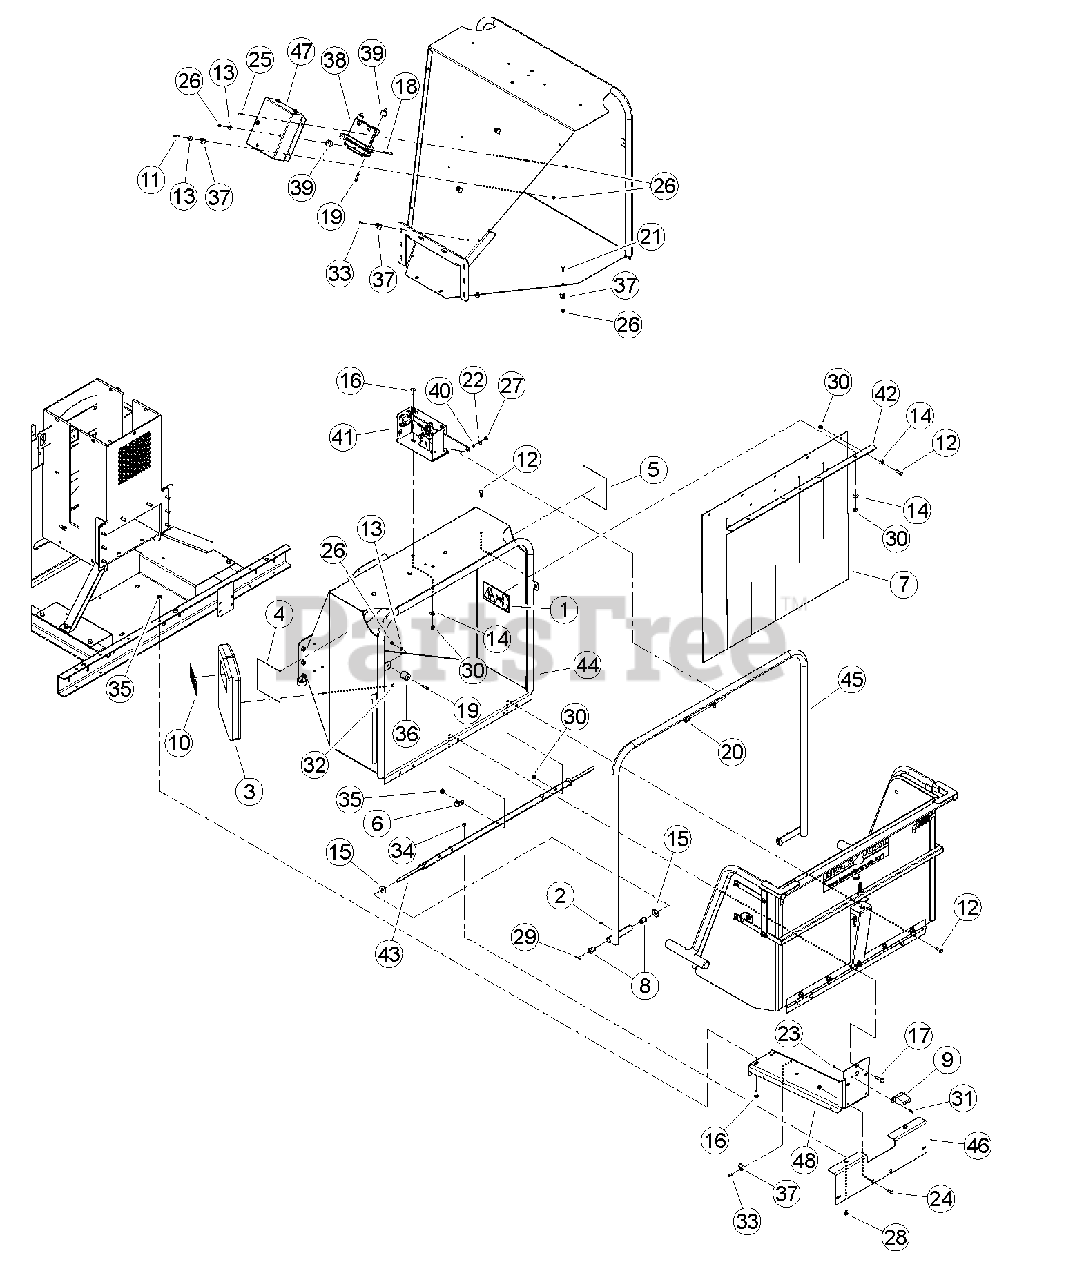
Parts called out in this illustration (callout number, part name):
1	DECAL, BLADE DANGER ISO
2	FITTING, 1/4 SELF-TAP GREASE
3	CONTAINER, INSTR. MANUAL
4	DECAL, FEED POSITION
5	DECAL, FEED POSITION
6	CLAMP, 9/16 COATED
7	FLAP, CHUTE
8	BUSHING, 1/2 X 1 FLANGE LUBE
9	LIGHT, LICENSE PLATE
10	DECAL, MUTILINGUAL MANUAL
11	BOLT, 1/4 X 1 GR5 HEX HD ZP
12	BOLT, 3/8 X 1 HEX HD GR5 ZP
13	WASHER, 1/4" FLAT ZP
14	WASHER, 3/8" FLAT ZP
15	WASHER, 1/2" FLAT ZP
16	BOLT, 3/8 X 1" GR5 CRG NC ZP
17	BOLT, 3/8 X 1-1/4 FLANGE NC
18	BOLT, 1/4 X 2-1/4 G5 HCS ZP
19	BOLT, 1/4-20 X 1-1/4 GR5 HHCS MAGNI 565 SILVER
20	BOLT, 5/16 X 1" GR5 HHCS NC ZP
21	BOLT, 1/4 X 1 GR5 CRG NC ZP
22	WASHER, 5/16" FLAT ZP
23	NUT, 8-32 NYLOCK
24	BOLT, 5/16 X 1" GR5 CRG ZP
25	BOLT, 1/4 X 5/8" HHCS GR5 ZP
26	NUT, 1/4" NE NYLOCK ZP
27	NUT, 5/16" NE NYLOCK ZP
28	BOLT, 5/16 X 3/4 GR5 CRG NC ZP
29	PIN, 1/8 X 1.00 ZP COTTER
30	NUT, 3/8" NE NYLOCK ZP
31	SCREW, MCH #10-24 X 3/4" PAN HD PH ZP
32	RIVET, AL BLIND 1/4 X 1/2 DOME HEAD
33	RIVET, AL BLIND 1/4 X 3/4 DOME HEAD
34	NUT, 5/16-18 NYLOCKFLANGE
35	NUT, 3/8-16 NYLOCK FLANGE
36	BUMPER, RECESSED RUBBER
37	CLAMP, CABLE MOUNT
38	CONTROLLER, PLUS 1 CHIPPER
39	BUMPER, 1" OD W/1/4" STUD
40	SPACER, IDLER PIVOT
41	ASSEMBLY, "CE" SWITCH BOX
42	SUPPORT, CHIPPER FLAP
43	WELDMENT, CONTROL PIVOT
44	WELDMENT, CHIPPER CHUTE
45	WELDMENT, CONTROL ARM
46	BRACKET, EUROPEAN LICENSE
47	ENCLOSURE, PLUS 1 MOUNT
48	ASSEMBLY, CHUTE/SPARE SUPPORT 6IN
